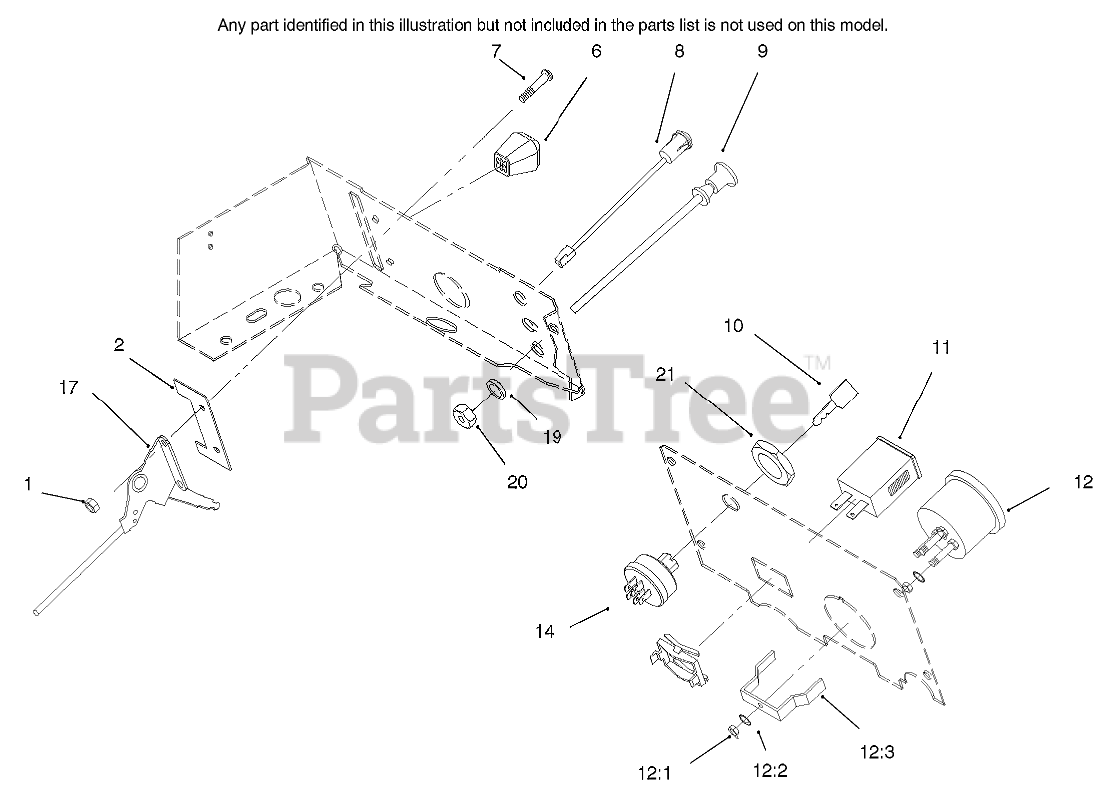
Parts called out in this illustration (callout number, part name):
1	Nut
2	STOP-THROTTLE
7	SCRW-PHC
8	LIGHT-INDICATOR
9	CHOKE CONTROL ASM
10	KEY-IGNITION
11	HOURMETER
12	VOLTMETER
12:1	NUT-HEX
12:2	WASHER-LOCK
12:3	CLAMP-MOUNTING
14	SWITCH-IGNITION
17	THROTTLE CONTROL ASM
19	WASHER-FLAT
20	NUT-HEX PALNUT
